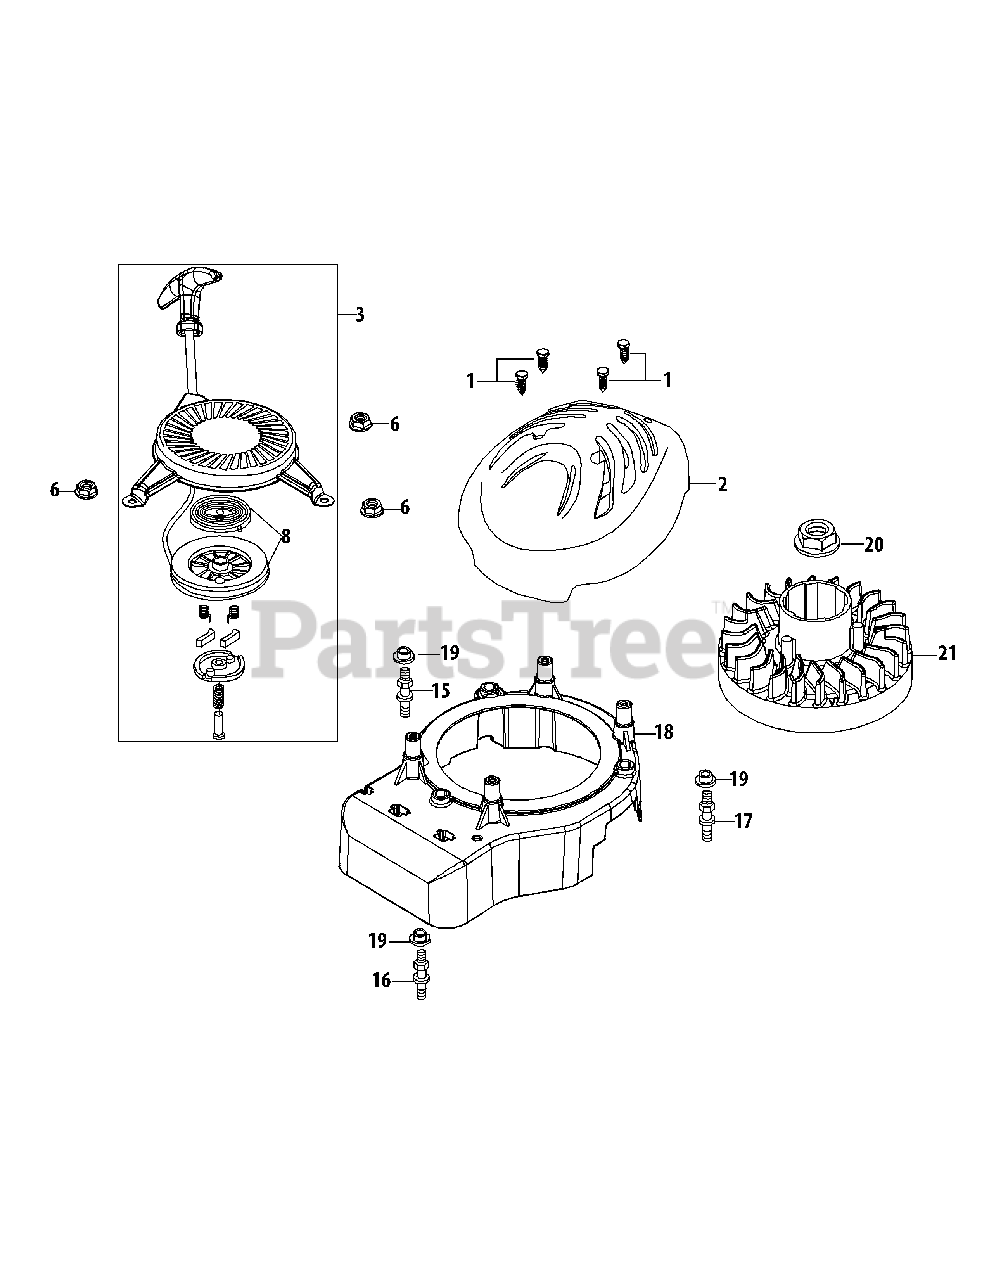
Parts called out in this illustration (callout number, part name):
1	Screw, #12-16 X 1.00"
2	Outer Shroud
3	Recoil Starter Assembly
6	Nut M6 X 10 Mm
8	Recoil Spring and Pulley Ass'y
15	Stud Left/Black
16	Stud Front/Unmarked
17	Stud Right/White
18	Inner Shroud
19	Engine Shroud Spacer
20	Flywheel Nut M14
